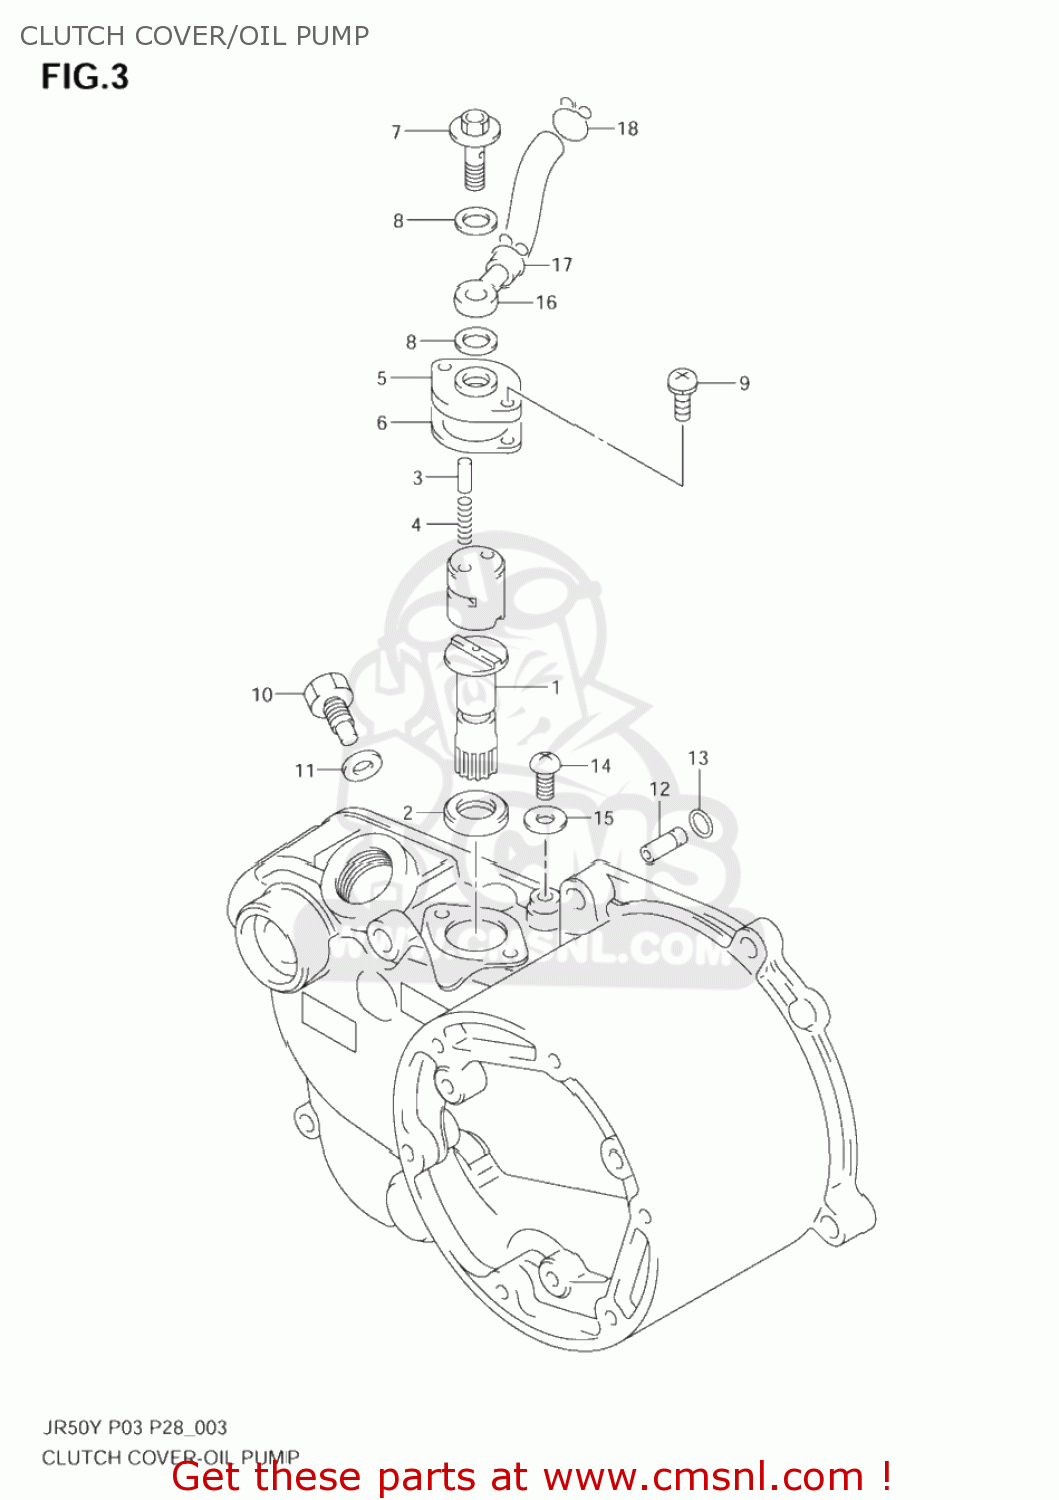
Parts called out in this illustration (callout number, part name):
1	GEAR,OIL PUMP DRIVE
2	SEAL,OIL(12X18.5X3)
3	PIN(2.3X7.5)
4	SPRING
5	CAM,OIL PUMP
6	GASKET,OIL PUMP (NAS)
7	UNION BOLT
8	GASKET(6.2X11X1).2 (NAS)
9	SCREW
10	BOLT(6X10)
11	WASHER
12	VALVE,CRANK CHECK
13	O RING(D:1.05,ID:3.1)
14	SCREW
15	GASKET(5X9.5X1) (NAS)
16	HOSE,INLET
17	CLIP
18	CLIP
